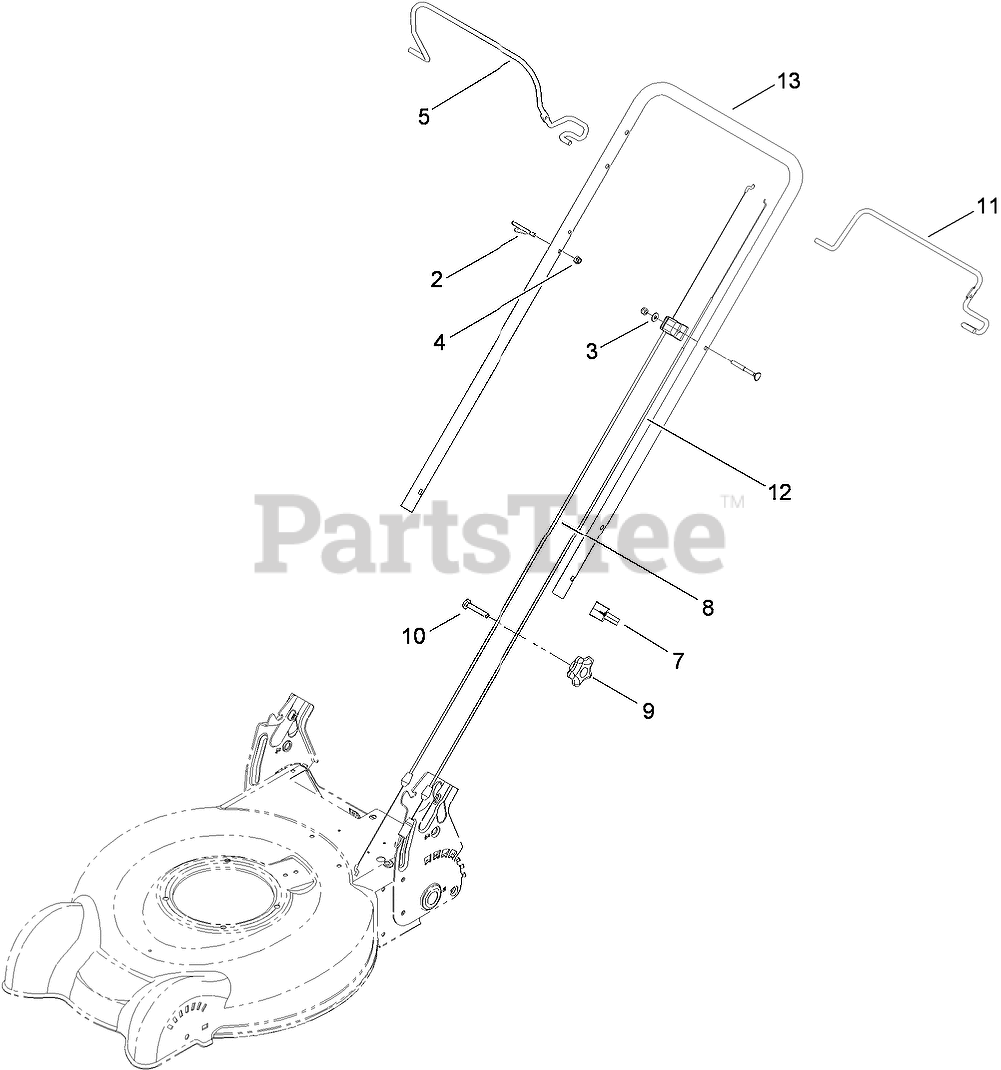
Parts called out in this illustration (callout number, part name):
2	GUIDE-ROPE
3	WASHER-FLAT
4	NUT-LOCK, NI
5	BAIL-BRAKE, 2-BAIL FLAT
7	GUIDE-CABLE
8	CABLE-BRAKE
9	KNOB-HANDLE
10	Screw-CARR
11	BAIL-TRACTION, 2-BAIL FLAT
12	CABLE-TRACTION
13	HANDLE-UPPER
